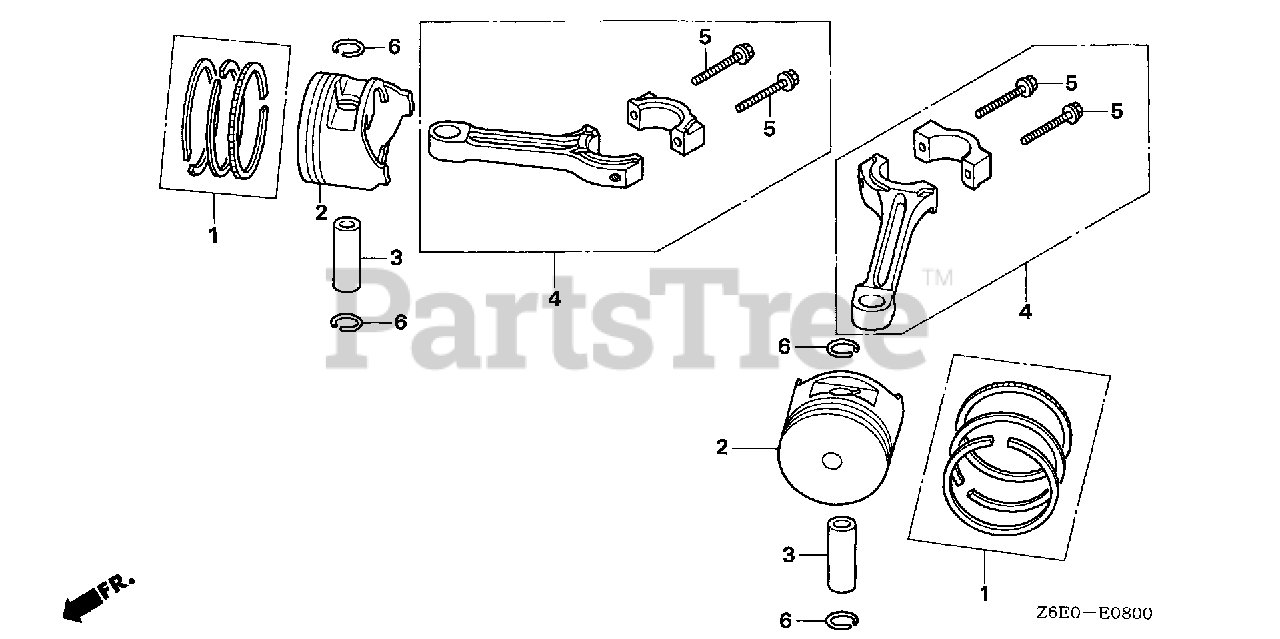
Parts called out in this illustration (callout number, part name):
1	RING SET, PISTON (STD) (NIPPON)
1	RING SET, PISTON (0.25) (NIPPON)
1	RING SET, PISTON (0.50) (NIPPON)
1	RING SET, PISTON (0.75) (NIPPON)
2	PISTON (STD)
2	PISTON (0.25)
2	PISTON (0.50)
2	PISTON (0.75)
3	PIN, PISTON
4	ROD ASSY., CONNECTING
5	BOLT, CONNECTING ROD (6X37)
6	CLIP, PISTON PIN (18MM)
